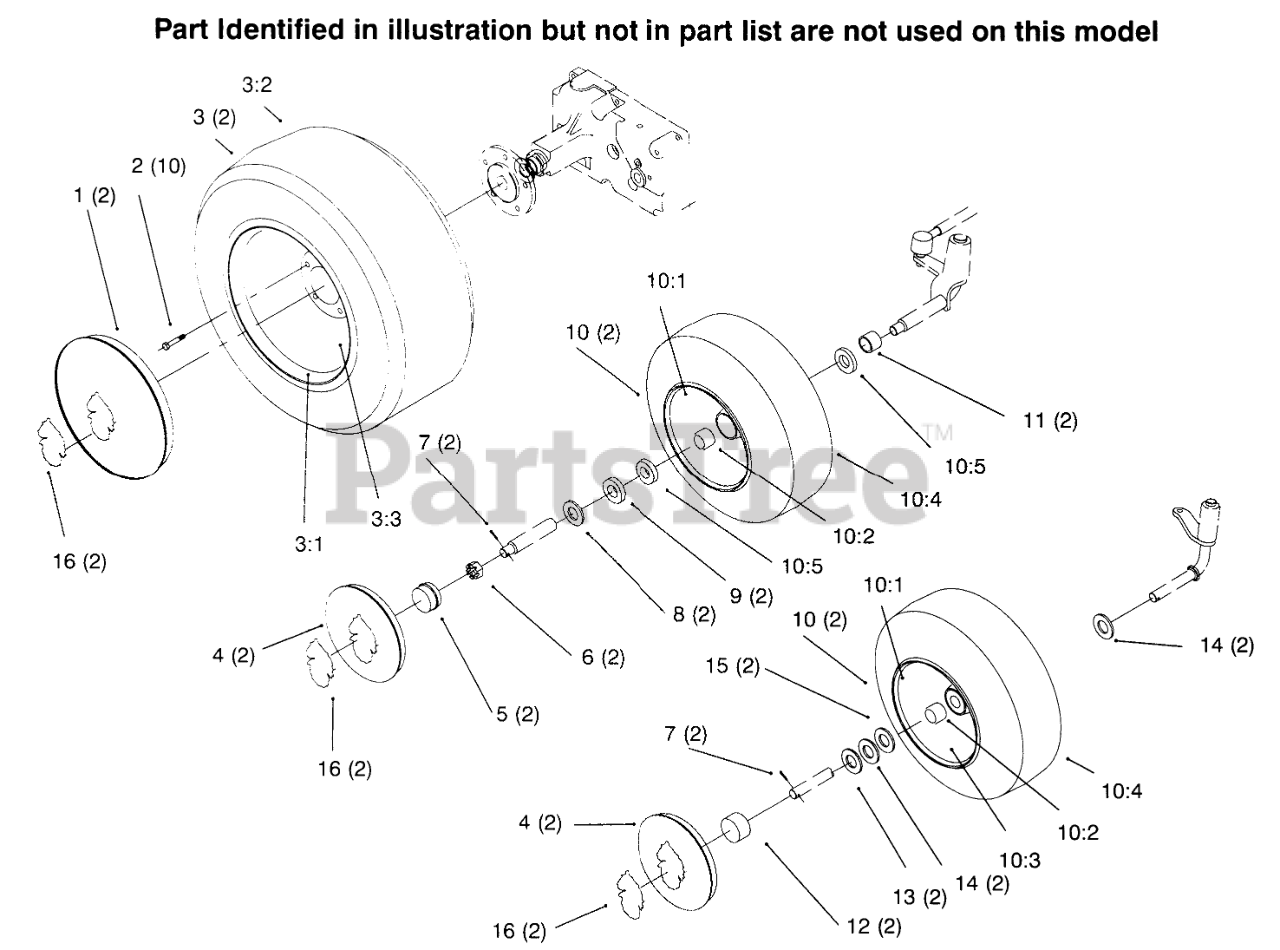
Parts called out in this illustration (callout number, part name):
2	BOLT-LUG
3	ASM-Wheel & Tire
3:1	WHEEL
3:2	TIRE
3:3	VALVE
7	PIN-COTTER
10	FRONT WHEEL ASM
10:2	BEARING-WHEEL
10:3	VALVE
10:4	Tire (16 x 6.5-8) 2-Ply -2 Wheel Axel
12	HUBCAP
13	WASHER WHEEL
14	WASHER
15	WASHER-SHIM
